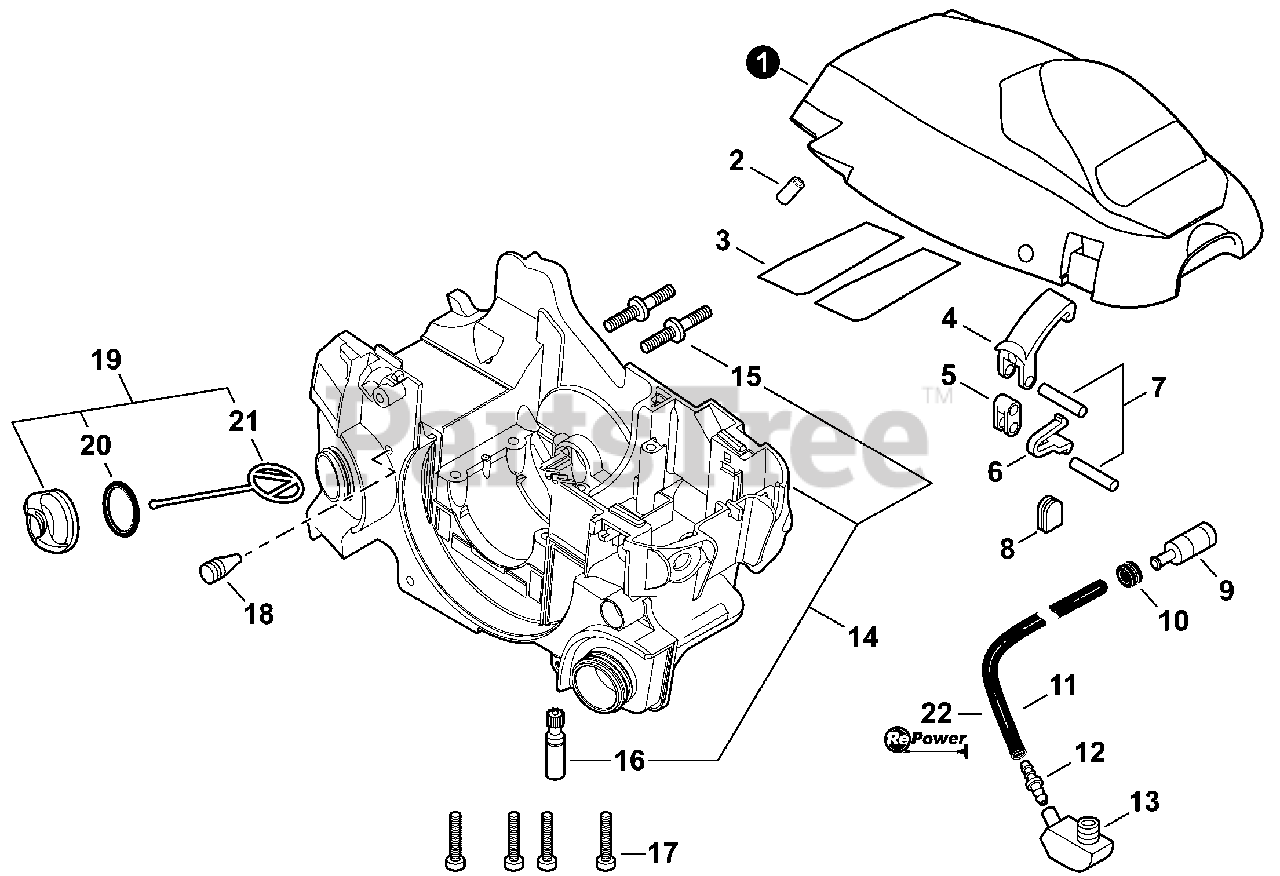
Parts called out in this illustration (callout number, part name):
1	COVER, ENGINE
2	BUSHING 3×7×10
3	SHIELD, HEAT
4	LATCH, ENGINE COVER
7	PIN
9	FILTER, OIL
10	GROMMET
11	PIPE 3×6×185 MM BLACK
12	CONNECTOR, PIPE
13	GROMMET, OIL
14	HOUSING ASSY, ENGINE
15	BOLT, STUD 8
16	AUTO-OILER ASSY
17	BOLT, TORX 5×30
18	VENT ASSY
19	CAP ASSY - BLACK
20	O-RING 18
21	CONNECTOR, CAP L= 60 MM
22	BULK PIPE - 3×6 MM BLACK (4 PIECES×2 M)
